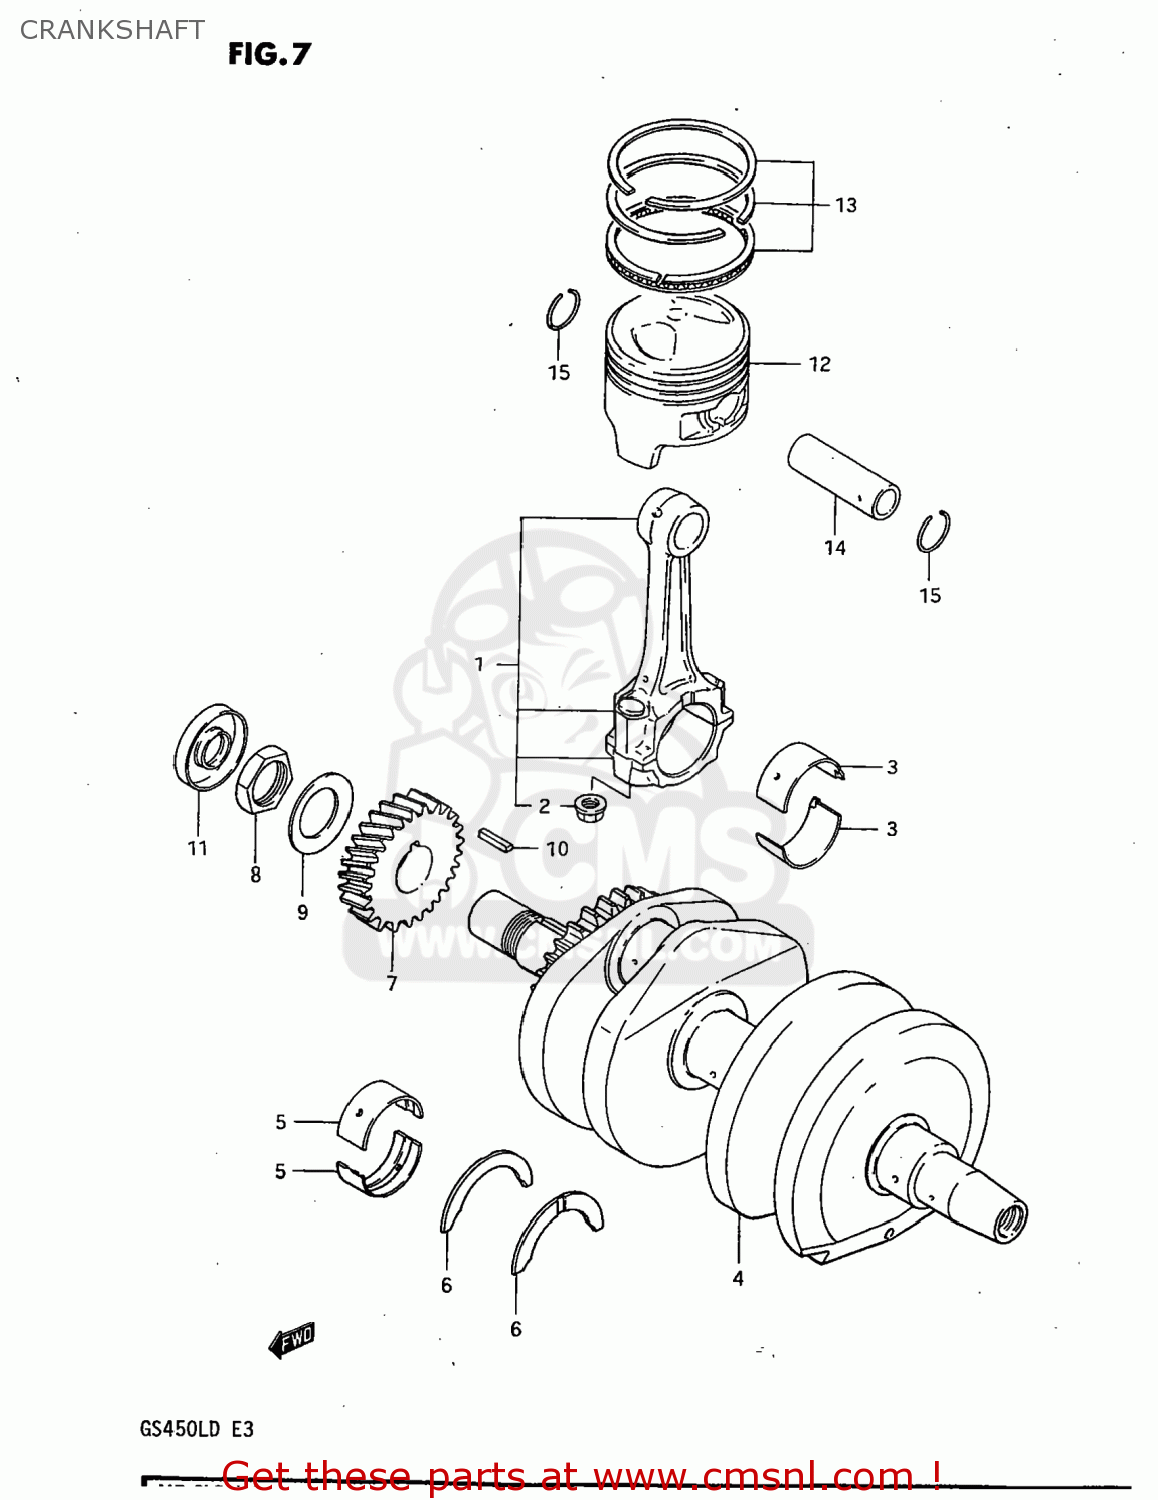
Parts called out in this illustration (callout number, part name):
1	ROD ASSEMBLY,CONNECTING
2	NUT
3	BEARING,CRANK PIN
4	CRANKSHAFT
5	METAL CRANKSHAFT
6	BEARING,CRANK THRUST
7	GEAR,PRIMARY DRIVE NO.28
8	NUT
9	WASHER
10	KEY
11	OIL SEAL
12	PISTON
13	RING SET,PISTON
14	PIN,PISTON (18MM)
15	CIRCLIP
